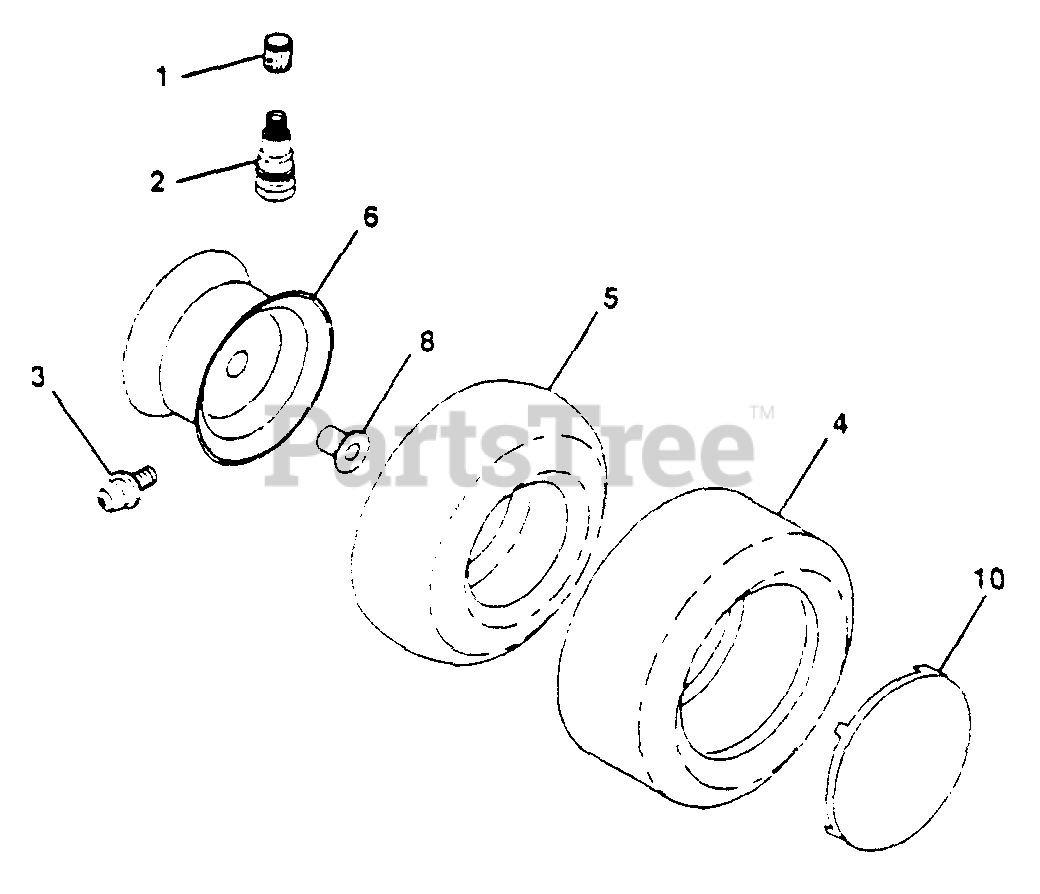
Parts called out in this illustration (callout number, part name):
1	Cap Valve Tire
2	Stem Valve
3	Fitting Grease
4	Tire F Ts 15 X 6 0 - 6 Service
4	Tire R Ts 18x9 5-8 C Service
5	Tube Front
5	Tube Rear
6	Rim Asm 8" rear White Service
6	Rim Asm Front 6"
8	Bearing Flange
10	Cover Wheel 6" white
10	Cover Wheel 8" white
